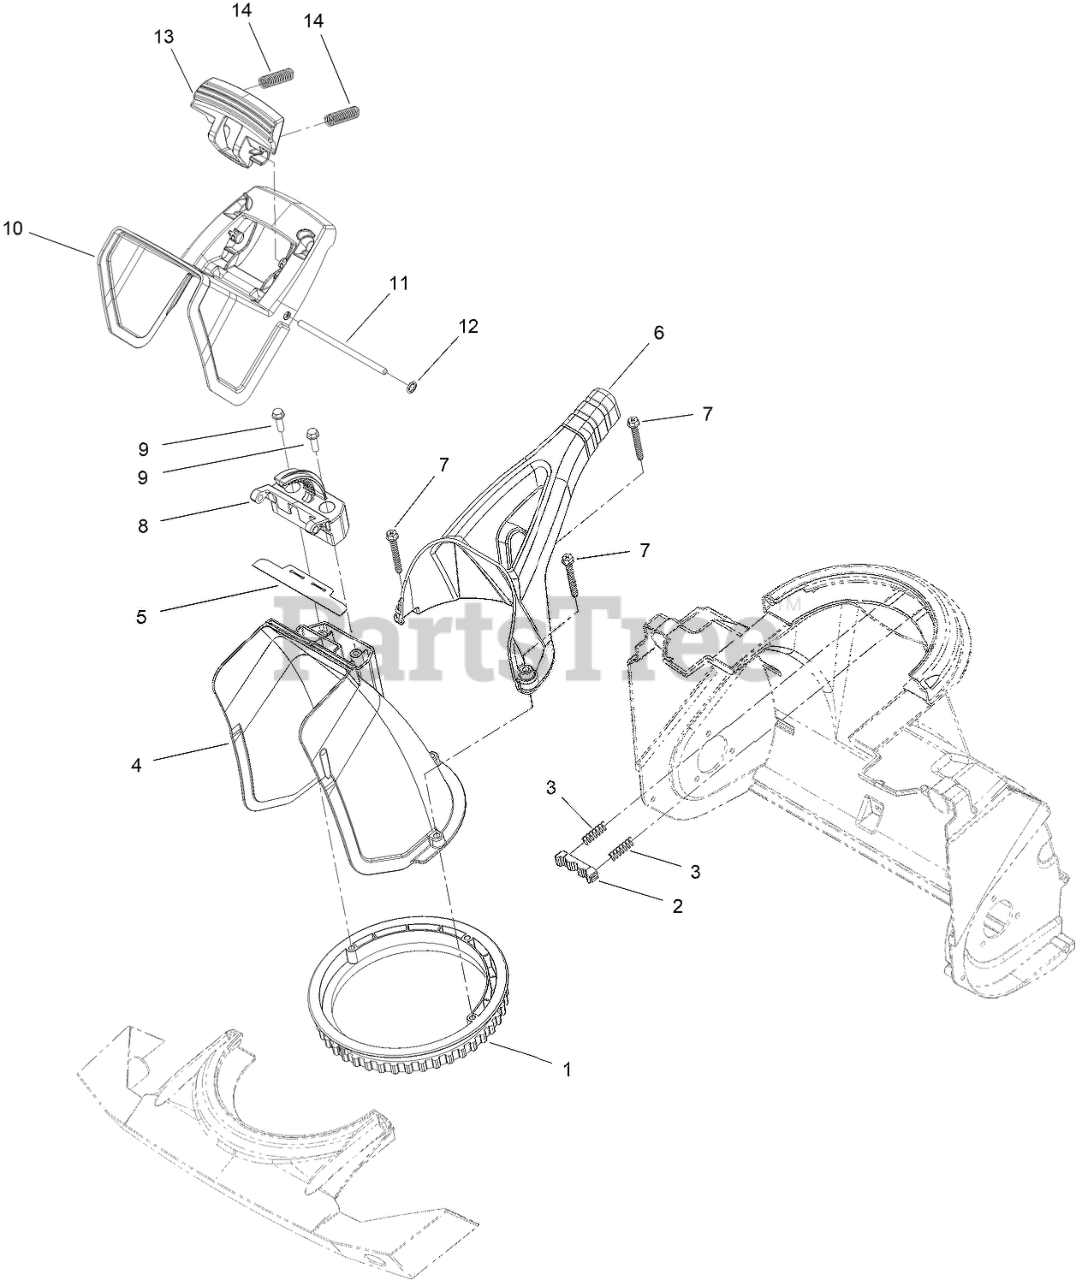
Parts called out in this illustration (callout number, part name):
1	RING-CHUTE
2	DETENT-CHUTE
3	SPRING-COMPRESSION
5	SEAL-DEFLECTOR
6	HANDLE-CHUTE
7	SCREW-HWH, PLASTITE
8	HINGE-RATCHET, DEFLECTOR
9	SCREW-PLASTITE, HWH
10	DEFLECTOR-CHUTE, CE
11	HINGE PIN-DEFLECTOR
12	RING-RETAINING
13	TRIGGER-DEFLECTOR
14	SPRING-COMPRESSION
